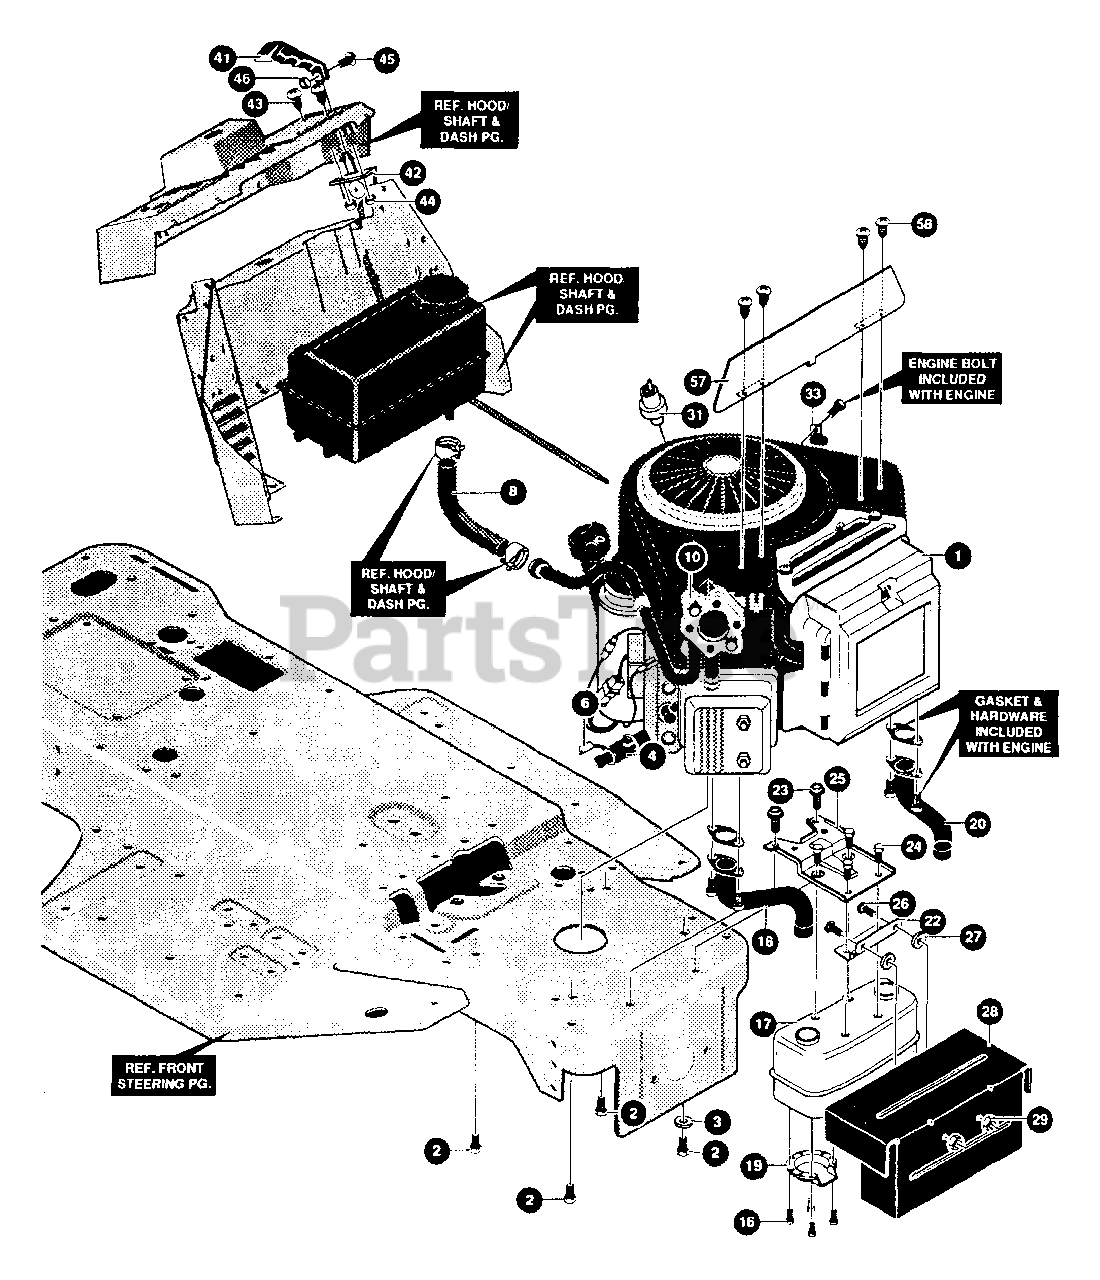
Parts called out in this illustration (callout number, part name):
1	14-16HP VANGUARD
2	SCREW, 3/8-16X1.25 WAHHTAPBLKP
3	WASHER, EXLK .384X.69X.04
4	NIPPLE 3/8-18 NPT X 4" ZINC
6	CAP PIPE 3/8-18 NPT ZN PL
8	TUBING, .25X.50X BULK GAS LINE
10	REGULATOR, VOLTAGE BS W/O SENSOR
16	SCREW, #8-32X.38 HHWATAP
17	MUFFLR 14/18 TWIN NLSN22785C
18	EXHAUST TUBE 15HP RH B&S VANG
19	DEFLECTOR SIDE OUT (BS222573)
20	EXHAUST TUBE 15HP LH B&S VANG
22	BRACKET, TRANSAXLE
23	SCREW, 5/16-18X.50 WAHHTAP
24	SCREW, 1/4-20X.75 WAHHTAP
25	BRACKET, MUFFLER
26	BOLT, 5/16-18X.63 CARRLN
27	PUSHNUT, 5/16 BOLT RETAINER
28	SHIELD, MUFFLER HEAT TWIN
29	NUT 5/16-18 HXWDFLLK
31	OIL SENSOR, B&S TWIN CYL
33	RETAINER .31IDX.62X.03 WERE
41	KNOB, THROTTLE CTL MOLD
42	THROTTLE CONTROL ERO 18 TWIN
43	SCREW, 10-24X.63PHPNMA
44	NUT #10-24 HXHDNYLK
45	SCREW, #8-32X.38 PHPNMA
46	NUT, #8-32 REGHEX
57	HEAT SHIELD V/G LT EURO
58	SCREW, 10-16X.50 DRILLTITE
